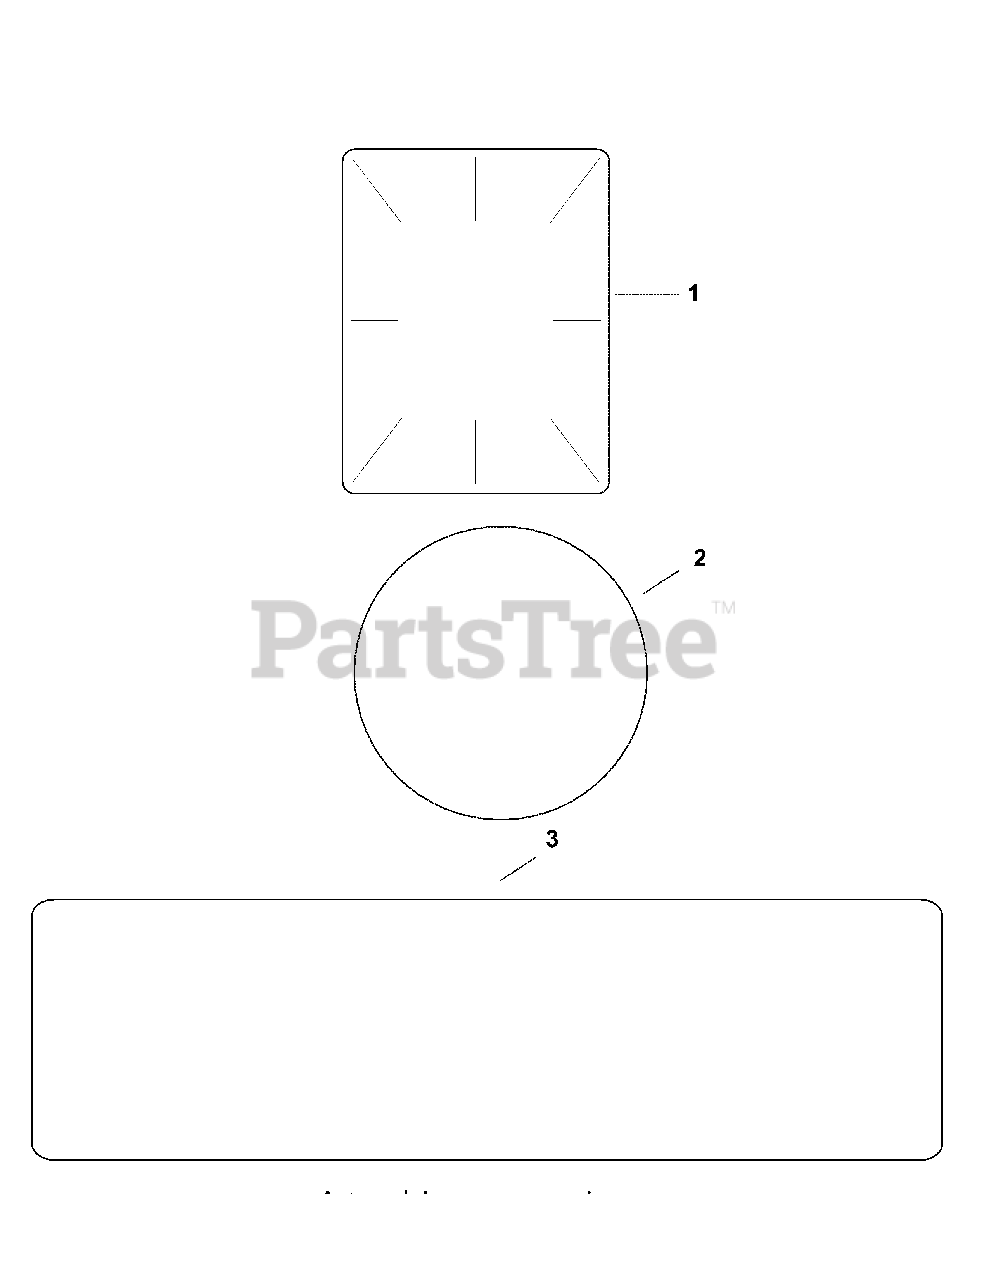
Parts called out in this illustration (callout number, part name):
1	Decal, Clear Laminate
2	Decal, Grass Screen
3	Decal, Command 23HP
